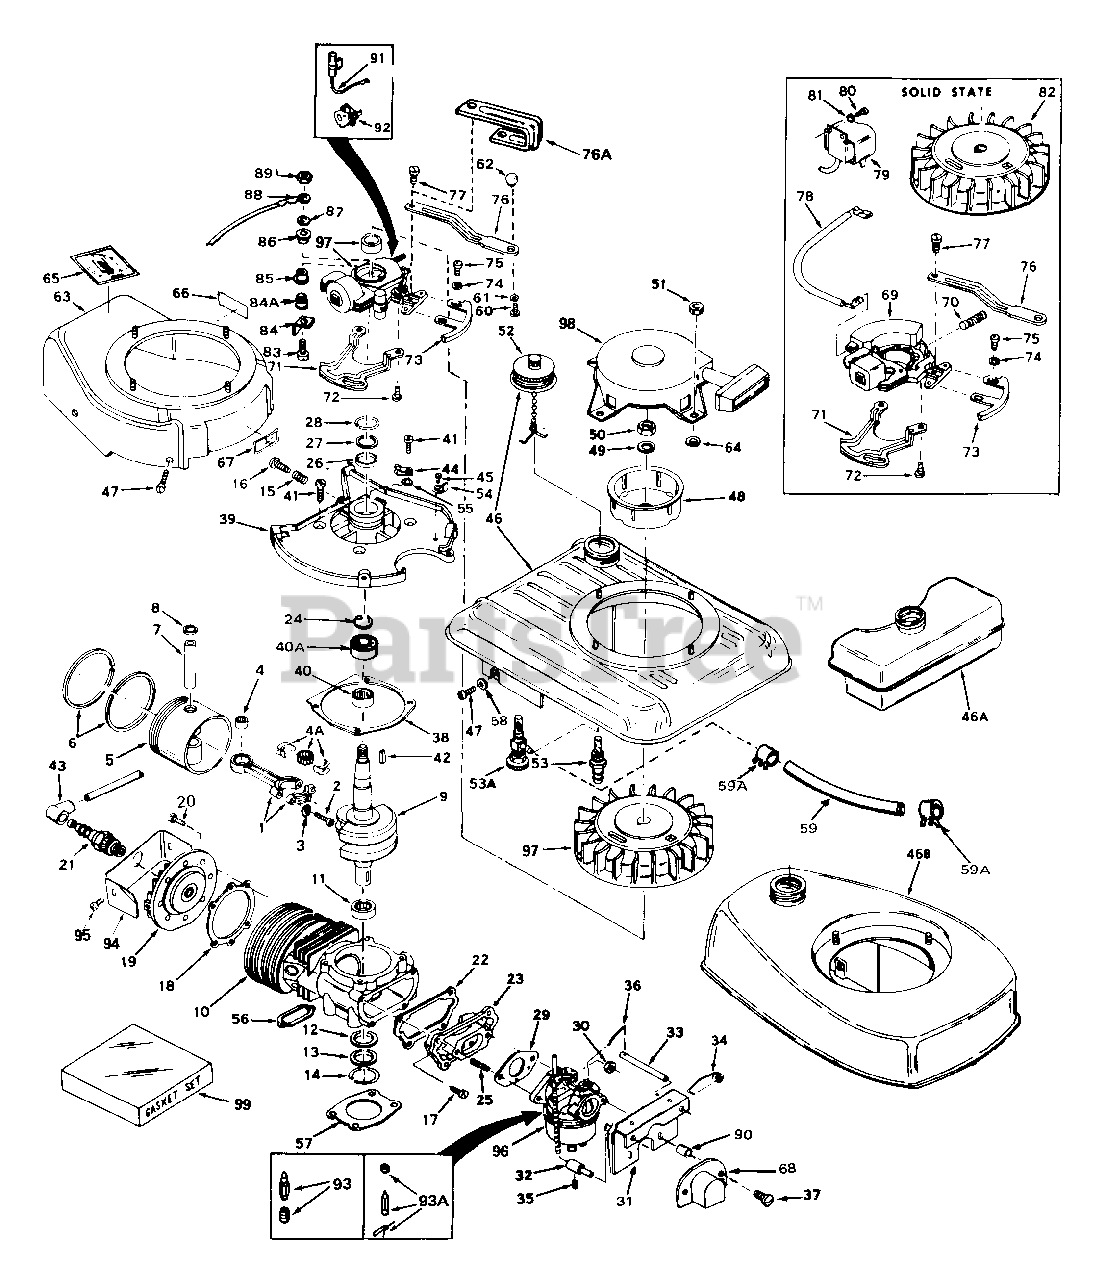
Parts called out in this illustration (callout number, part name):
1	"Rod Assy., Connecting
2	Screw, Connecting rod
4	Bearing, Cartridge
4A	Bearing & Liner Set, Needle (37 needl es)
5	Piston & Pin Assy.
6	Ring Set, Piston
7	Pin, Piston
8	Ring, Piston pin retaining
9	Crankshaft
10	Block Assy., Cylinder
11	Bearing, Needle
12	Seal, Crankshaft
13	Retainer, Crankshaft seal
14	Ring, Crankshaft retainer seal
16	Screw, Rd. hd., 8-32 x 7/8
17	Screw, Int. torx hd., 10-24 x 1/2
18	Gasket, Cylinder head
19	Head, Cylinder
20	Screw, Torx pan hd., 1/4-20 x 3/4
21	Resistor Spark Plug (Champion RJ-12YC or
22	Gasket, Reed plate
23	Plate Assy., Reed
24	Ring, Ball bearing retaining
25	Stud, Carburetor
26	Seal, Crankshaft
27	Retainer, Crankshaft seal
28	Ring, Crankshaft seal retainer
29	Gasket, Carburetor
30	Nut, Flange whizlock, 1/4-28
31	Bracket, Control
32	Rod, Idle adjustment
33	Rod, Choke
34	Spring, Choke rod
35	Screw, Hex Socket hd. set, 6-32 x 3/1 6
36	Link, Choke shaft
37	Screw, Fil. hd. Sems, 10-32 x 7/8
38	Gasket, Housing base
39	Base Assy., Housing
40	Bearing, Needle
41	Screw, Hex washer hd. Durlok, 1/4-20 x 5/8
42	Key, Flywheel
43	Cover, Spark plug
44	Clip, Cable
45	Screw, Pan flex hd., 10-24 x 3/8
46B	Tank, Fuel
47	Screw, Hex washer hd., 1/4-20 x 3/4
48	Cup, Starter
49	Washer, Belleville
50	Nut, Jam Hex
51	Nut, Flange whizlock, 1/4-28
52	Cap, Fuel tank
53A	Valve, Fuel strainer & shut off
54	Stop, Control lever
59	Line, Fuel (8-1/4" long)
59	Line, Fuel (16" long)
59	Line, Fuel (32" long)
68	Baffle, Air
70	Screw Assy., Friction
75	Screw, Torx pan flex hd., 6-32 x 3/8
76	Lever, Control
77	Screw, Pan flex hd., 10-24 x 3/8
83	Screw, Pan hd., 6-32 x 3/4
84	Terminal
85	Washer, Insulating
86	Washer, Insulating
87	Washer, Flat 5/32
88	Wire, Cut off
89	Nut & Lockwasher, 6-32
91	Condenser
92	Contact Assy., Breaker
93A	Inlet Needle, Seat & Clip Assy.
96	Carburetor
98	Starter, Rewind
99	Gasket Set
